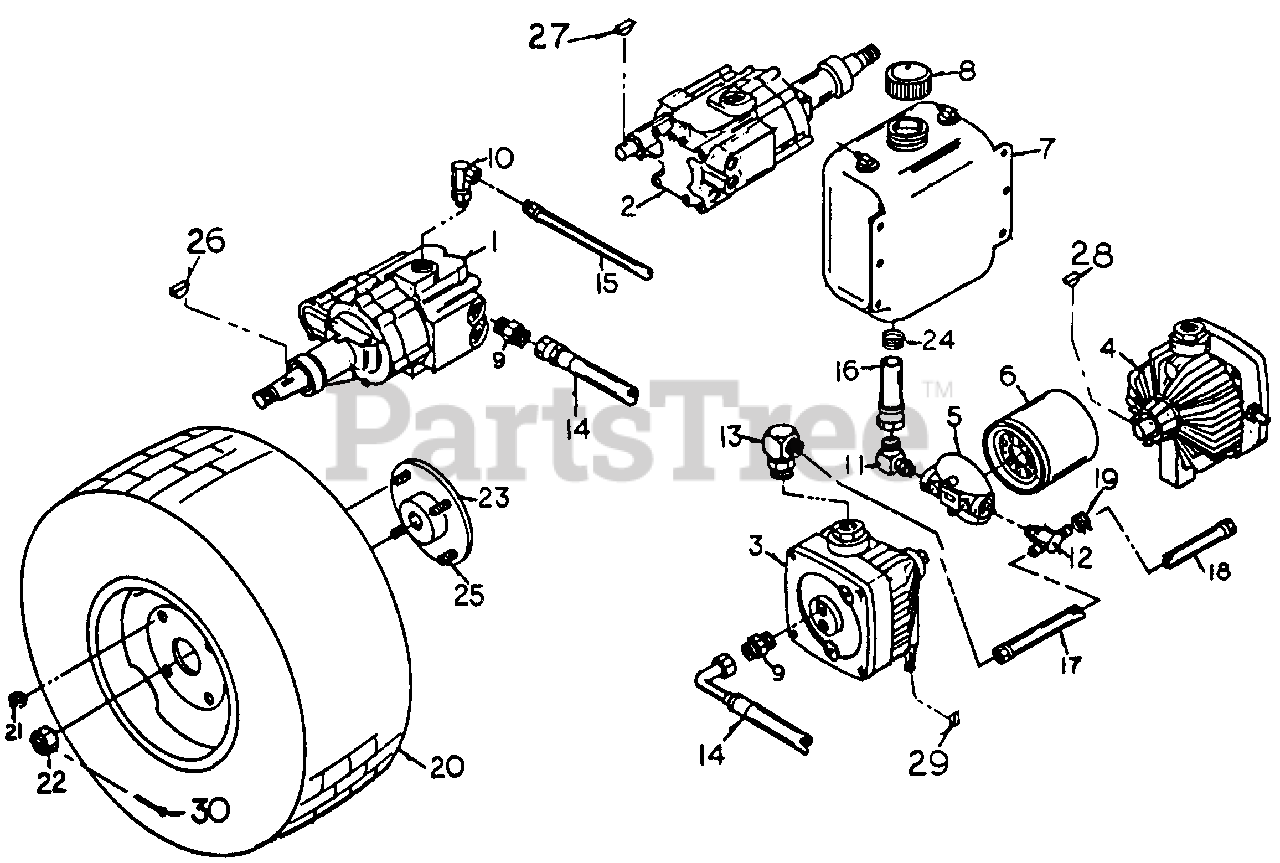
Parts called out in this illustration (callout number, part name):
1	Wheel Motor, LH
2	Wheel Motor, RH
3	Pump, LH
4	Pump, RH
5	Housing, Oil Filter
6	Element, Oil Filter
7	3 Qt. 0il Tank
9	Male Tube, Male O-ring Adp.
10	Male O ring, 90ø Female Pipe Swivel Adp.
11	Male O-ring, 90ø Male Tube Adp.
12	Male O-ring, 1/2" Hose Barb Tee
13	Male O-ring, 90ø Male Tube Adp.
14	Hose, 1/2" ID x 28" Long
15	Hose, 1/4" ID x 24" Long, Easy Couple
16	Hose, 5/8" ID x 7" Long, Easy Couple
17	Hose, 1/2" ID x 15" Long, Easy Couple
18	Hose, 1/2" ID x 21" Long, Easy Couple
19	Hose Clamp, 1/2"
20	Wheel Ass'y., 18 x 9.50-8
21	Lug Nut, 1/2-20
22	Nut, Wheel Motor
23	4-Bolt Wheel Hub
24	Hose Clamp, 5/8"
25	Lug Bolt, 1/2-20 x 1 1/4"
26	Woodruff Key, 3/16" x 3/4"
27	Woodruff Key, 3/16" x 3/4"
28	Woodruff Key, 1/8" x 1/2"
29	Woodruff Key, 1/8" x 3/8"
30	Cotter Pin, 1/8" x 1 3/4"
